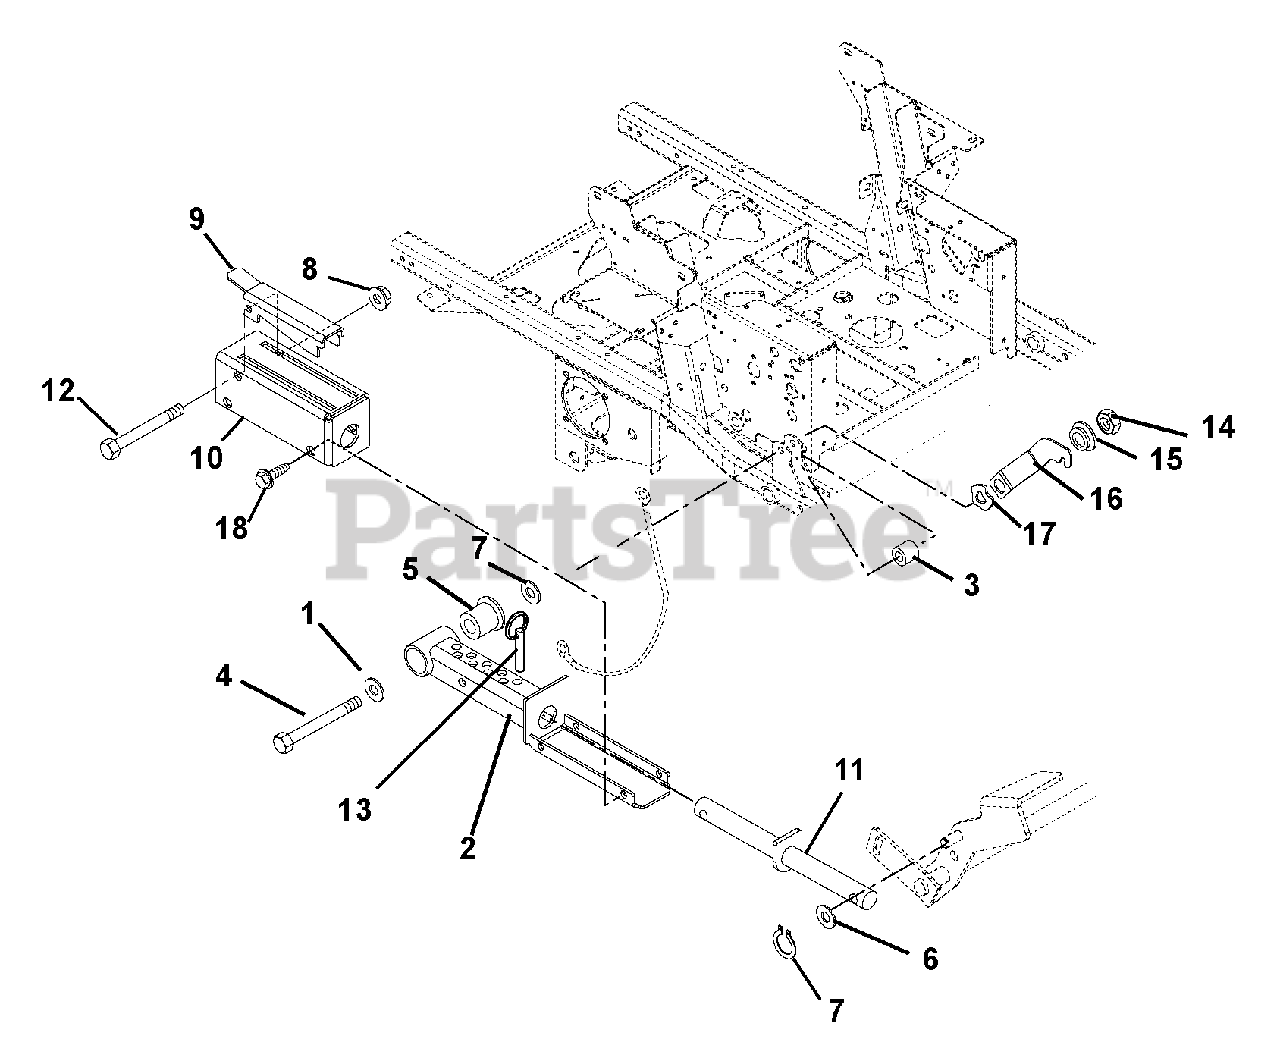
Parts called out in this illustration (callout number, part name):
1	Washer, Flat Steel .531 x 1.250 x .10
2	Weldment, Mechanical Lift
3	Bushing .516 x 1.00 x 1.05
4	Bolt, Hex .50-13 x 5.00 Grade 5
5	Bearing, Pedestal Powdered Metal
6	Washer, Flat Steel .656 x 1.310 x .095
7	Ring, Retaining External .625 x .050
8	Nut, Locking Top Flange .38-16
9	Lock-Up, Mechanical Lift
10	Weldment, Mechanical Lift Cover
11	Weldment, Mechanical Lift Shaft
12	Bolt, Hex .38-16 x 3.25 Grade 5
13	Pin, Spring Ball .375 O.D. x 1.50
14	Nut, Locking Top Flange .50-13
15	Bushing, Flange .515 x .75 x .275 x 1.12
16	Latch, Footboard
17	Washer, Wave .076 x 1.12 x .08
18	Screw, Tapping .38-16 x .50
